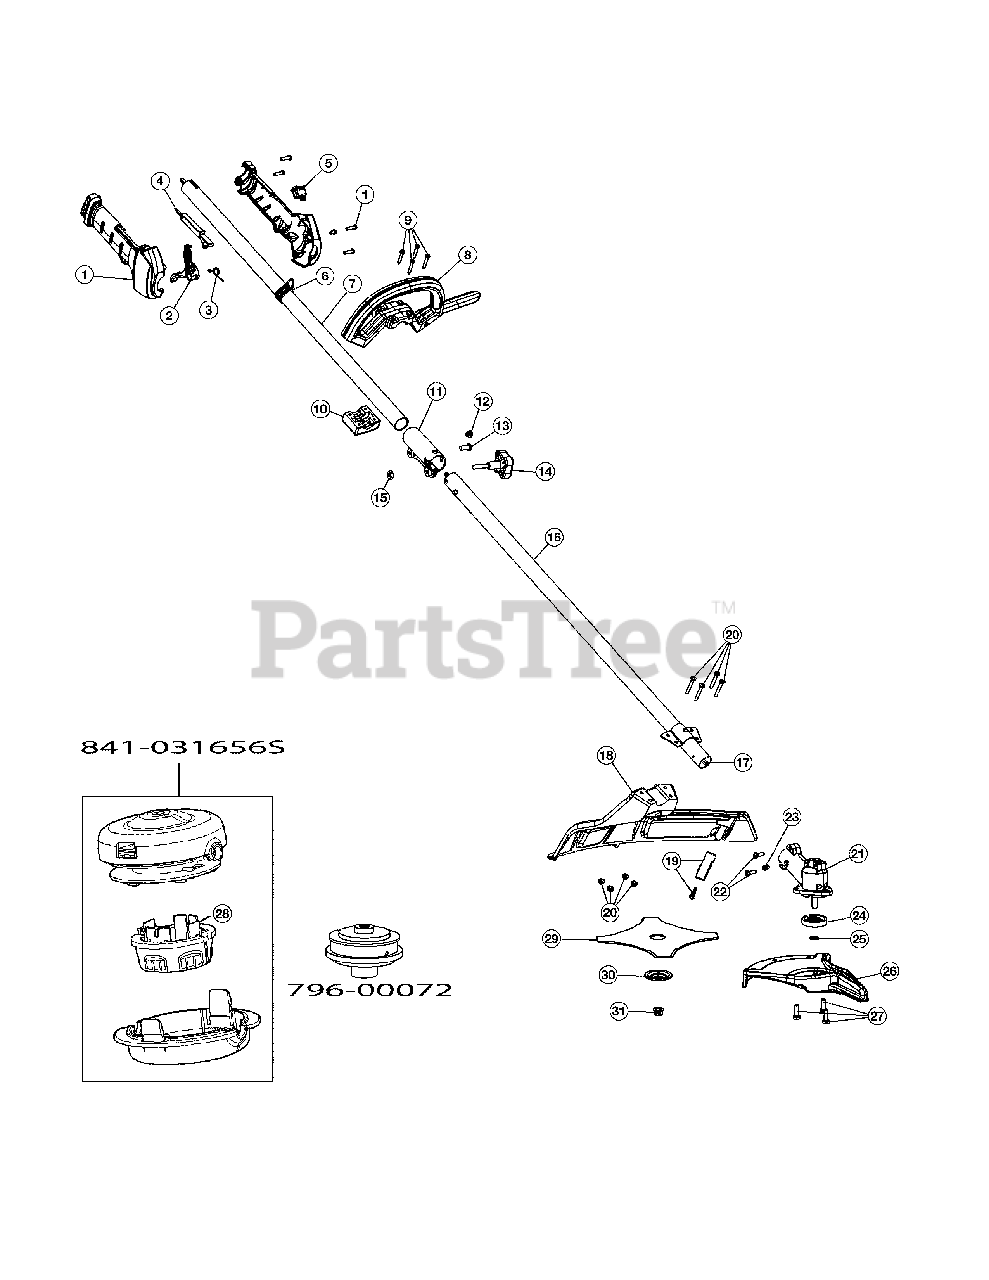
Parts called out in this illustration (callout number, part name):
1	Throttle Housing Assembly
2	Throttle Trigger
4	Throttle Lock-out
6	Shoulder Strap Clip
7	Upper Drive Shaft Housing Assembly
8	D-Handle Assembly
9	Handle Base
11	Split Boom Coupler
12	Coupler Anti-Rotation Screw
14	Adjustment Knob
15	Knob Retaining Nut
16	Lower Drive Shaft Housing Assembly
17	Lower Flexible Drive Shaft
18	Shield Assembly
19	Blade Assembly
20	Shield Mounting Screw & Nut
22	Gearbox Mounting Hardware
23	Anti-Rotation Screw
24	Blade Driver
26	Blade Shield
27	Blade Shield Mounting Hardware
29	4-Tooth Blade
30	Retaining Washer
796-00072	Cutting Head Assembly
841-031656S	Cutting Head Assembly
